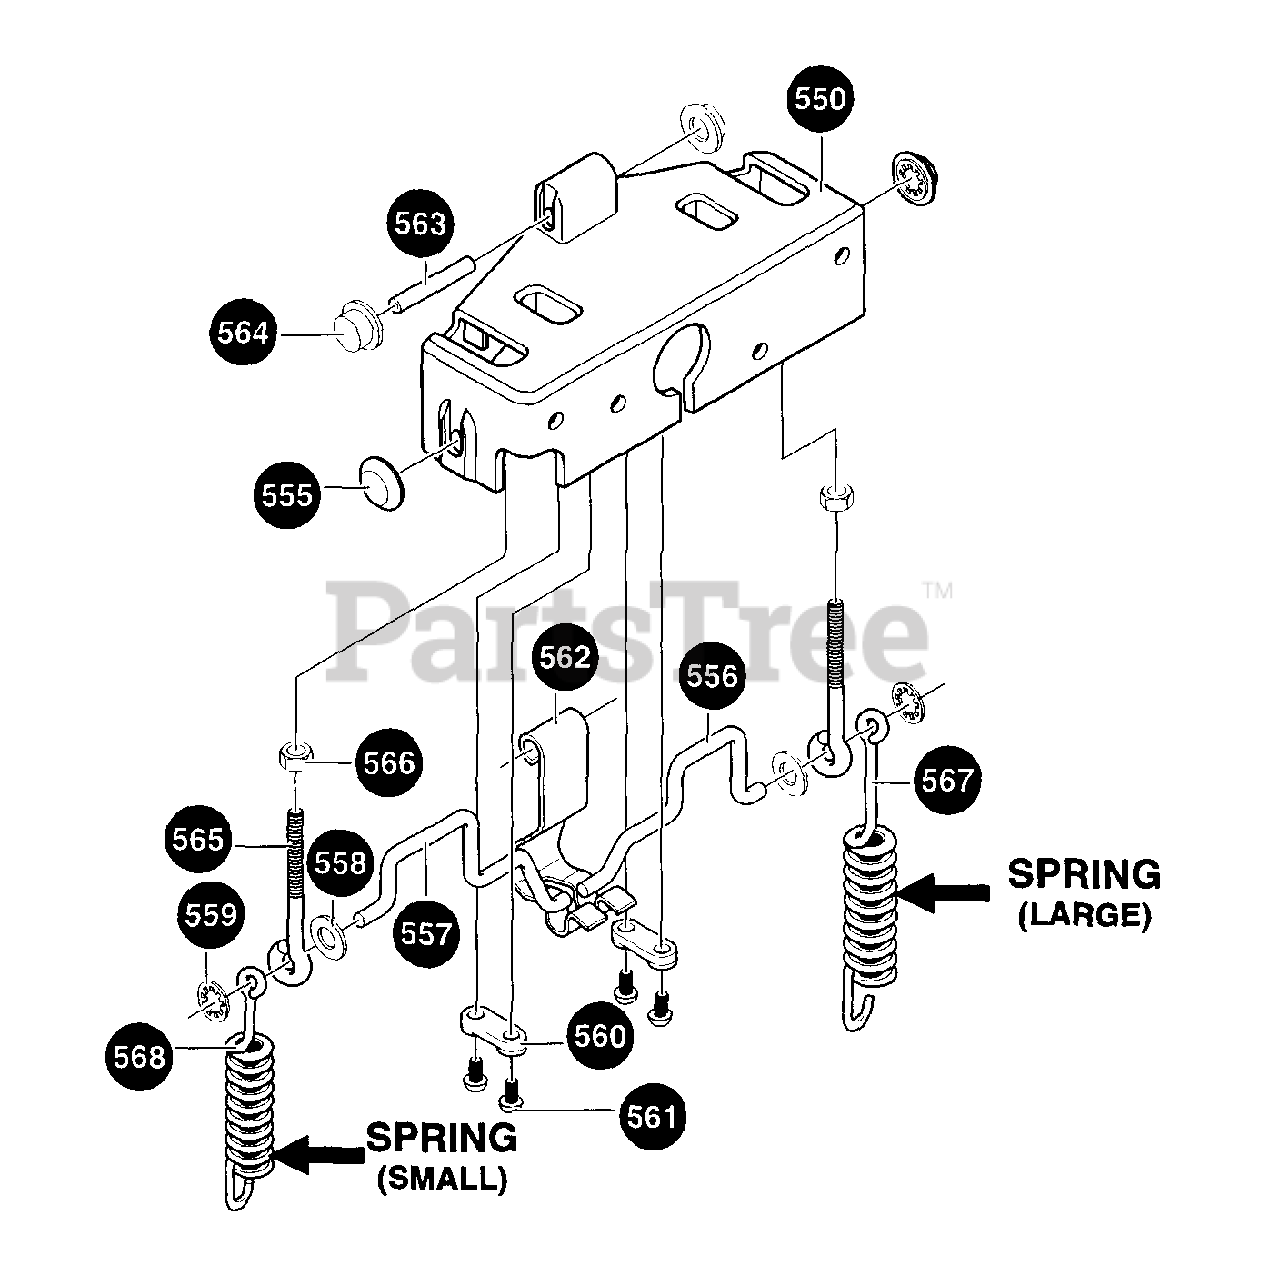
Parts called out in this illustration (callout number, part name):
550	HOUSING, SINGLE HAND
555	NUT, PUSH ON CAP 312 OD
556	CAM/LATCH, LH
557	CAM/LATCH, RH
558	WASHER, FLAT .344 X .69 X .065
559	RING, RETEX X TRU5115-31
560	CLAMP, SHC CAM FRAME MOUNTED
561	SCREW, #8 X .75 PANTAPPLAST
563	PIN, SPRING PIVOT SHC
564	NUT, PUSH ON 3/8"
566	NUT, #10-24 REGH
567	SPRf NG, DRIVE CLUTCH
568	SPRING, AUGER CLUTCH
